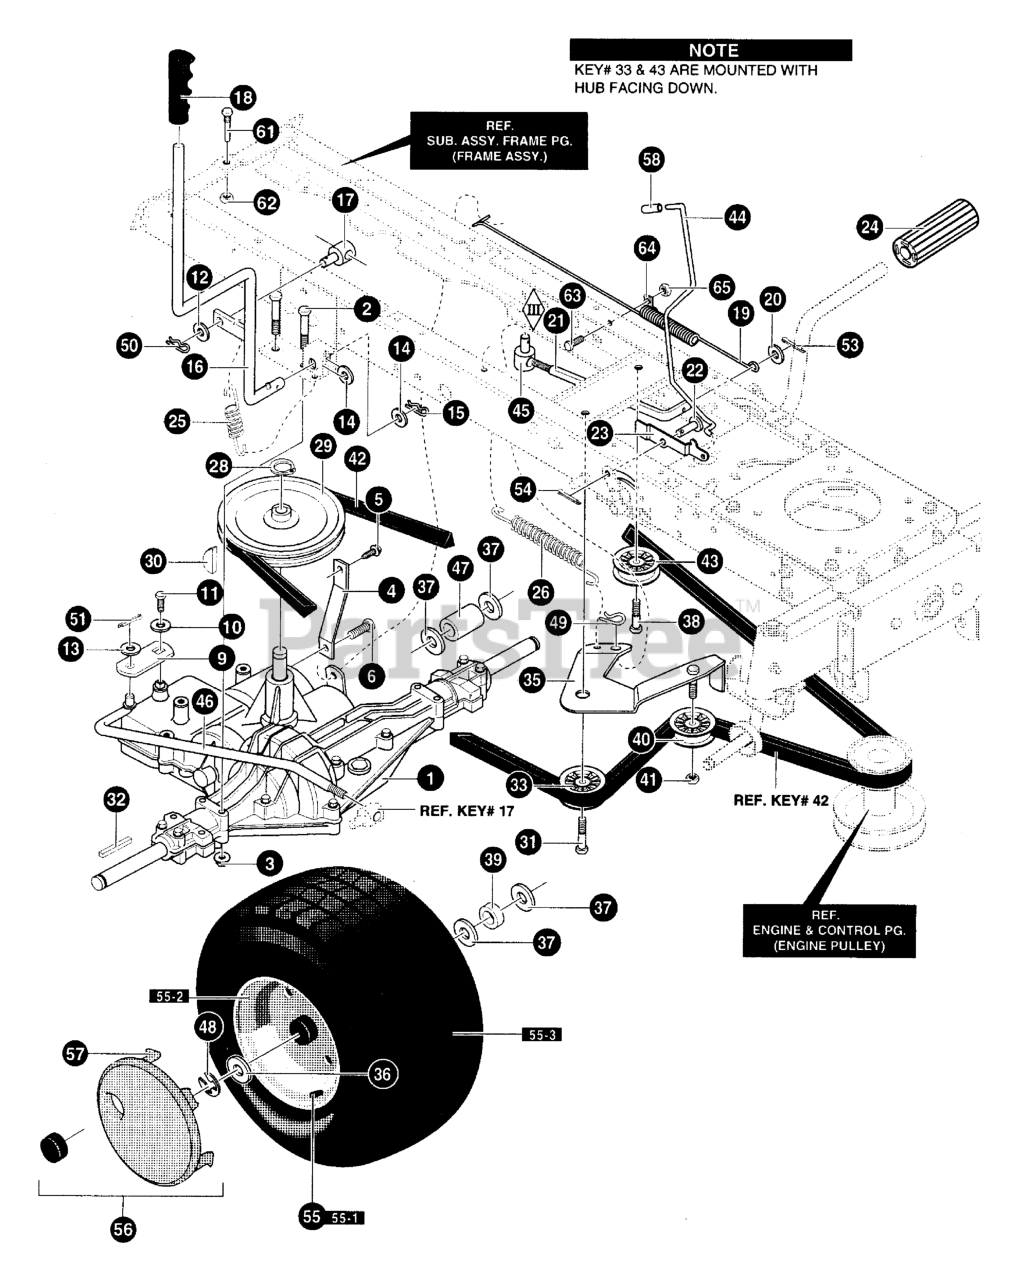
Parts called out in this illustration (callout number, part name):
2	SCREW, 5/16-18 x 2.50
3	NUT, 5/16-18 WDFLLK
4	BRACKET, STABILIZER
5	SCREW, 5/16-18 x 0.75
6	SCREW, 5/16-18 x 0.75 WAHHTAP
9	BRACKET,SHIFT
10	WASH ER,.750X.250 TRANSAXLE
11	SCREW, 1/4-28X.75
12	WASHER, FLAT .391X1.00X.125
13	WASHER, FLAT .406X .81X.066
14	WASHER, FLAT .515X .88X.064
15	PIN, HAIR.53DIAX1.62LG
16	SHIFT LEVER
17	NUT, ADJ. 3/8-16
18	GRIP, LIFT 1/2"
19	SPRING, BRAKE
20	WASHER, FLAT.328X1.06X.062
21	ROD, CLUTCH
22	PIN, CLEVIS
23	LATCH, PARK BRAKE
24	PEDAL,BRAKE/CLUTCH
26	SPRING, TENSION
28	RING, RETEX
29	PULLEY, 9.0 OD V4L
30	KEY, HI-PRO 606
31	SCREW, 3/8-16 x 1.25
32	KEY, SQUARE
33	PULLEY, IDLER
35	ASSY, IDLER ARM TRACTION
36	FLATWASHER.765X1.81X.059
37	WASHER, FLAT .755 ID
38	SCREW, 3/8-16 x 1.25
39	SPACER, WHEEL
40	PULLEY, IDLER 2.75 DIA
41	NUT, 3/8-16 HWDFLLK
42	BELT, V 4L 114.12
43	PULLEY, IDLER V41-3.00X.710
44	PARK BRAKE CONTROL ROD
45	NUT, 5/16-18X3/8 ADJUSTING
46	ROD, SHIFT LINK
47	SPACER, .87 X 2.25
48	E-RING.574IDX.050/.75
49	PIN, HAIR.53DIAX1.62LG
50	PIN, HAIR.38 DIAX1.64LG
51	PIN, COTTER.090 DIAX.75
53	PIN, COTTER.090 DIAX.75
54	PIN, COTTER.090 DIAX.75
55	TIRE & RIM
55-1	VALVE STEM.
55-2	RIM, CARL
55-3	TIRE, 20X8X8
56	HUBCAP, AXLE SHAFT
57	NOT USED ON THIS UNIT
58	CAP, DUMP VALVE ROD
61	SCREW GUIDE
62	NUT, 5/16-18 HEXWDFLLK WHIZ
63	SCREW, 1/4-20X .50
64	RETAINER, WIRE
65	NUT, 1/4-20 WDFLWHIZ-LK
